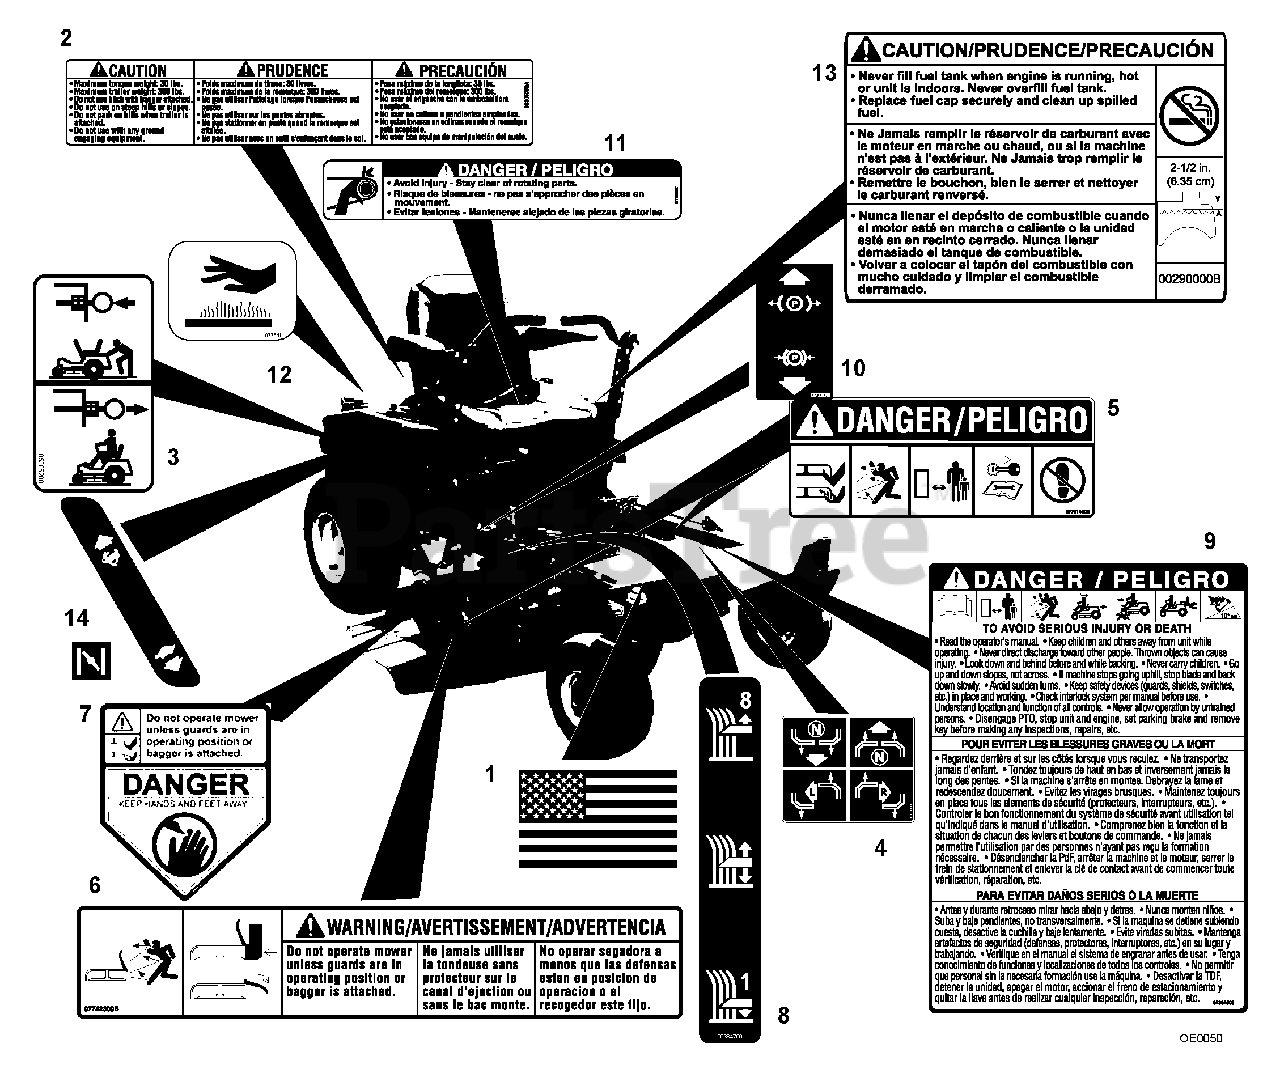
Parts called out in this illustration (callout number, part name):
1	Decal, American Flag
2	Decal, Trailer Hitch
3	Decal, Transmission Disconnect
4	Decal, Instructional Steering
5	Decal, Mower Pan Danger
6	Decal, Warning
7	Decal, CPSC Danger
8	Decal, Cut Height
9	Decal, Bilingual Danger
10	Decal, Parking Brake Lever
11	Decal, Danger
12	Decal, Hot Surface
13	Decal, Fuel Warning
14	Decal, Control
